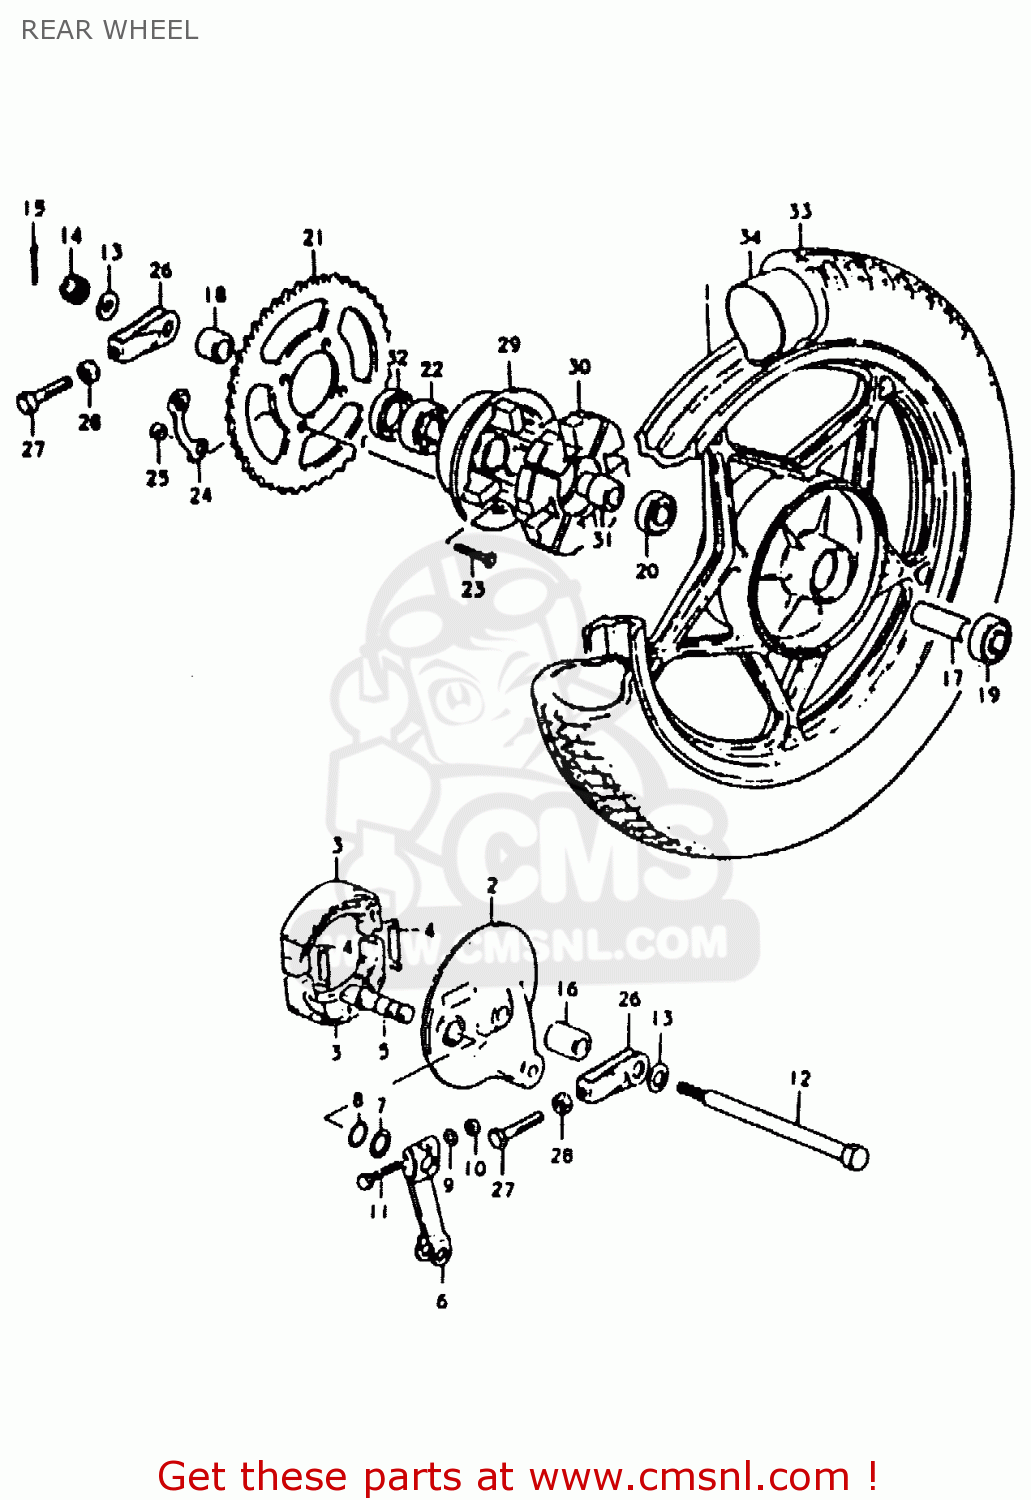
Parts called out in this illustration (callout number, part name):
1	WHEEL, REAR (J18X1.4 DOT)
2	PANEL, REAR HUB
3	SHOE,BRAKE
4	SPRING(L:34)
5	CAM,FRONT BRAKE
6	LEVER,RR BRAKE CAM
7	WASHER (14.5X22X1.6)
8	O-RING (D:2.4 ID:13.8)
9	WASHER
10	NUT
11	BOLT(6X33)
12	AXLE,FRONT
13	WASHER
14	NUT 12MM
15	COTTER PIN
16	SPACER, AXLE RH
17	SPACER (12.6X19X58)
18	SPACER 12X25X2
19	BEARING
20	BEARING
21	SPROCKET,RR(NT:45)
22	BEARING
23	BOLT(8X33.5)
24	WASHER
25	NUT
26	ADJUSTER,CHAIN,R
27	BOLT(6X38)
28	NUT
29	DRUM,RR SPROCKET MOUNTING
30	CUSHION,REAR DRUM
31	RETAINER,RR SPROCKET DRUM
32	SEAL OIL(25X40X6)
33	TIRE (2.50-18)
34	TUBE,INNER
